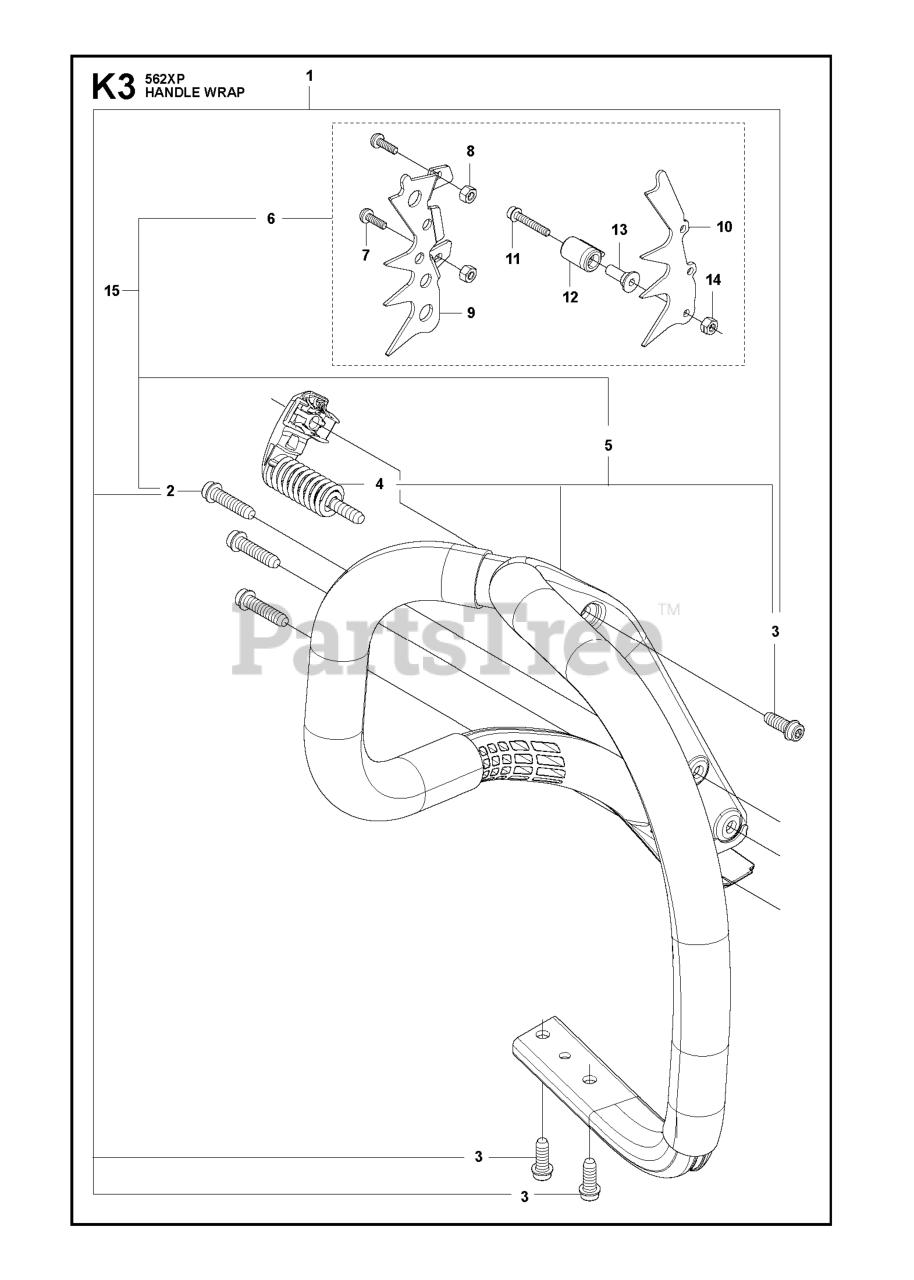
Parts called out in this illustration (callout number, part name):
1	HANDLE KIT WRAP
3	SCREW ITXSCFT PL6X16 T27 10.9
4	ANTIVIBRATION ELEMENT CYLINDER
5	FRONT HANDLE ASSY WRAP AROUND
6	SPIKE ASSY KIT
7	SCREW ITXPANM M5X16 T27 10.9
9	SPIKE, OUTER
10	SPIKES, INNER
13	CHAIN CATCHER
15	562XP WRAP KIT
